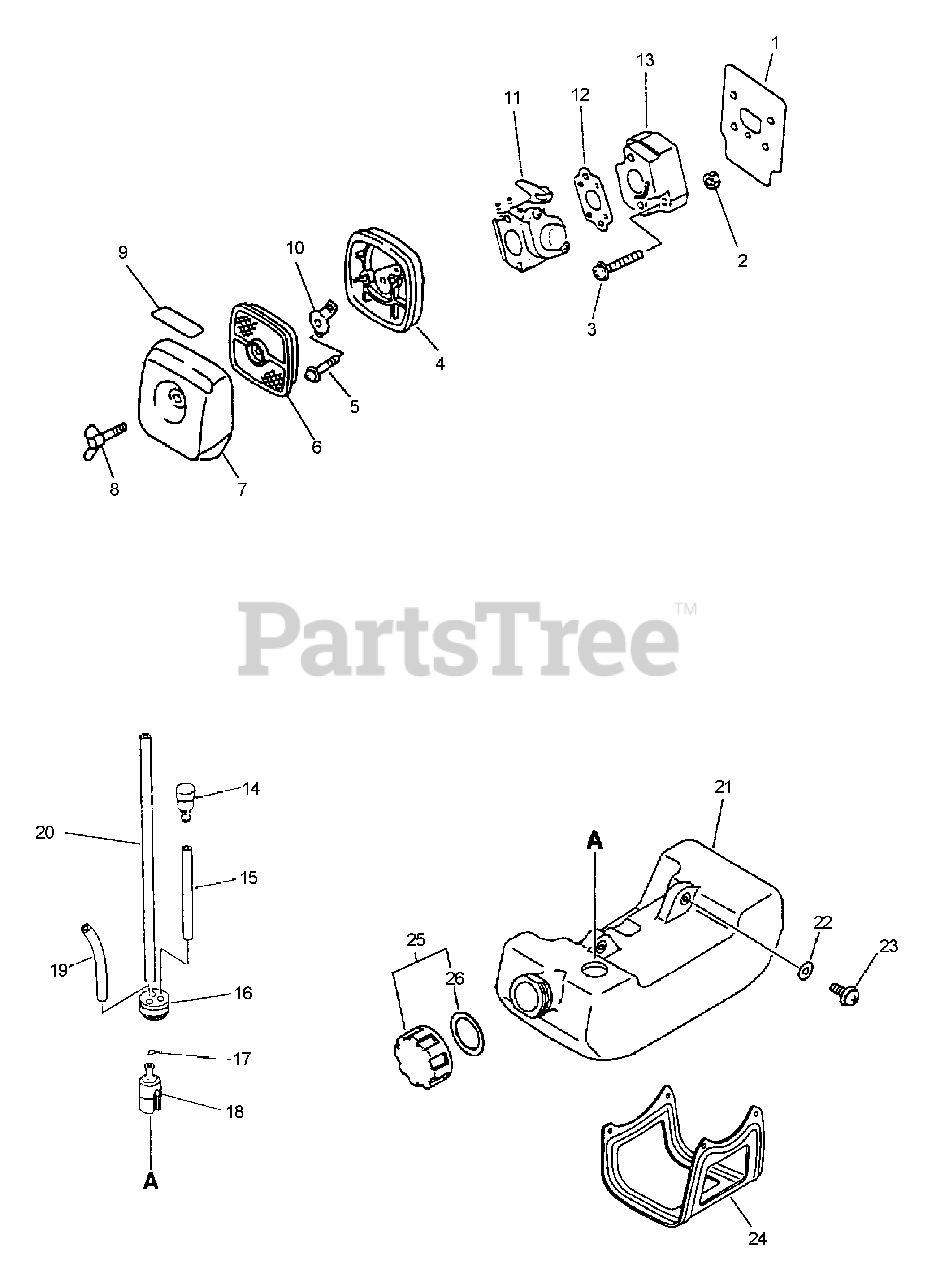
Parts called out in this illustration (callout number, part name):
1	SHIELD, INTAKE
3	SCREW - 5X20
4	AIR FILTER CASE ASSY
5	SCREW - 5X65
6	FILTER, AIR - SINGLE LAYER
7	COVER, AIR FILTER - BLACK
8	THUMBSCREW
9	LABEL - CHOKE
10	PLATE, PREVENT
11	CARBURETOR WT-424B
12	GASKET, INTAKE
13	INSULATOR, INTAKE
14	VENT, FUEL TANK
15	PIPE - 3X5X70 -- BLACK
16	GROMMET
17	CLIP - 6
18	FILTER, FUEL
19	PIPE - 3X6X90 -- CLEAR
20	PIPE - 3X5X180 -- BLACK
21	FUEL TANK ASSY
22	WASHER - 5
23	SCREW - 5X16
24	GUARD, FUEL TANK
25	CAP ASSY
26	GASKET, CAP
